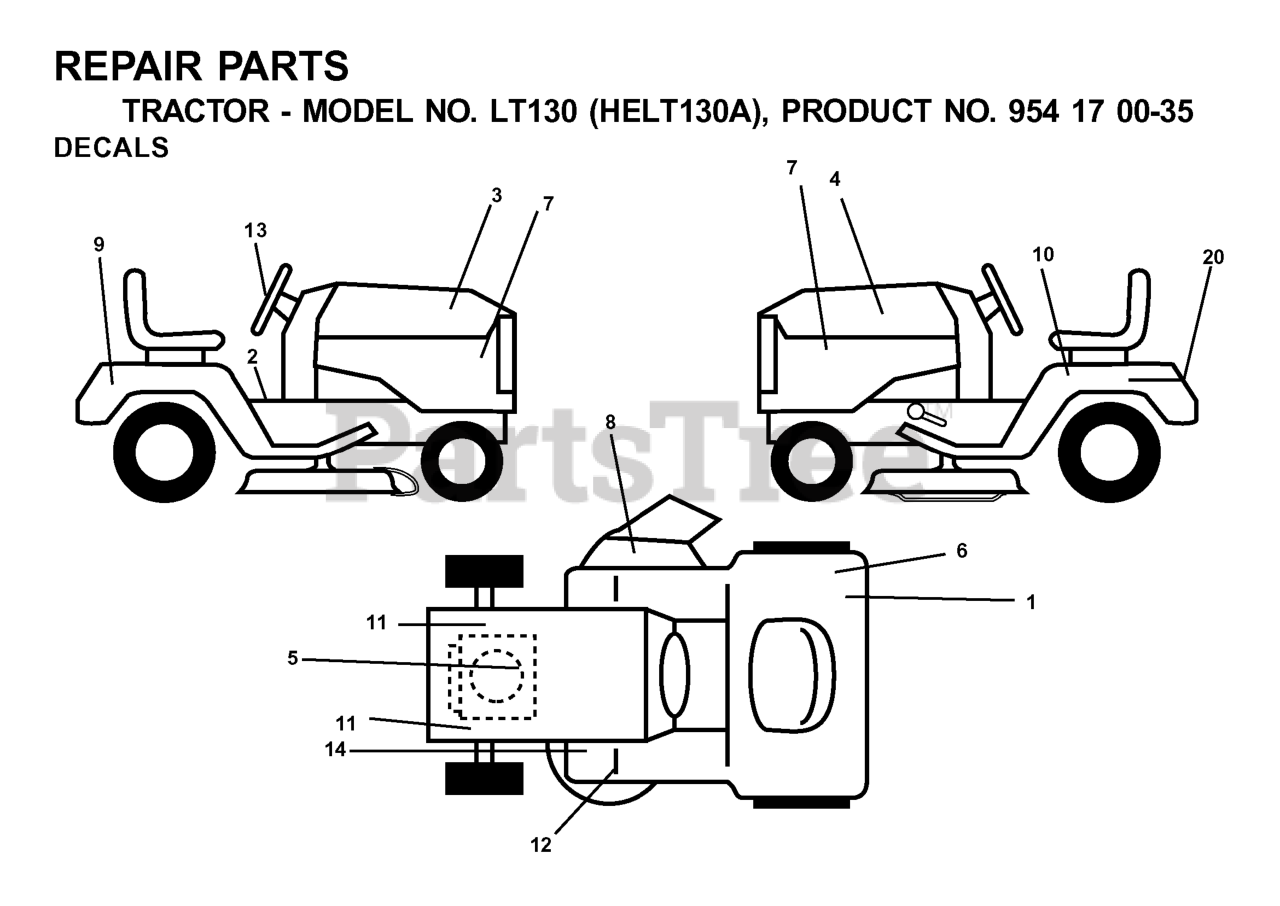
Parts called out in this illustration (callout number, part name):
1	DECAL CERTIFICATION
2	DECAL PARK BRAKE
3	DECAL HOOD RH LT130
4	DECAL HOOD LH LT130
5	DECAL HP ENGINE
6	DECAL EUROPE STANDARD CE
7	DECAL PNL SIDE
8	DECAL MOWER CUT/FINGER
9	DECAL FENDER HUSQ
10	DECAL READ OWNER'S MAN SYMS
12	DECAL
13	DECAL.WHEEL.STEERING.HUSQ.PERM
14	DECAL V-BELT SCHEMATIC
20	DECAL BTRY SYMBOLS
